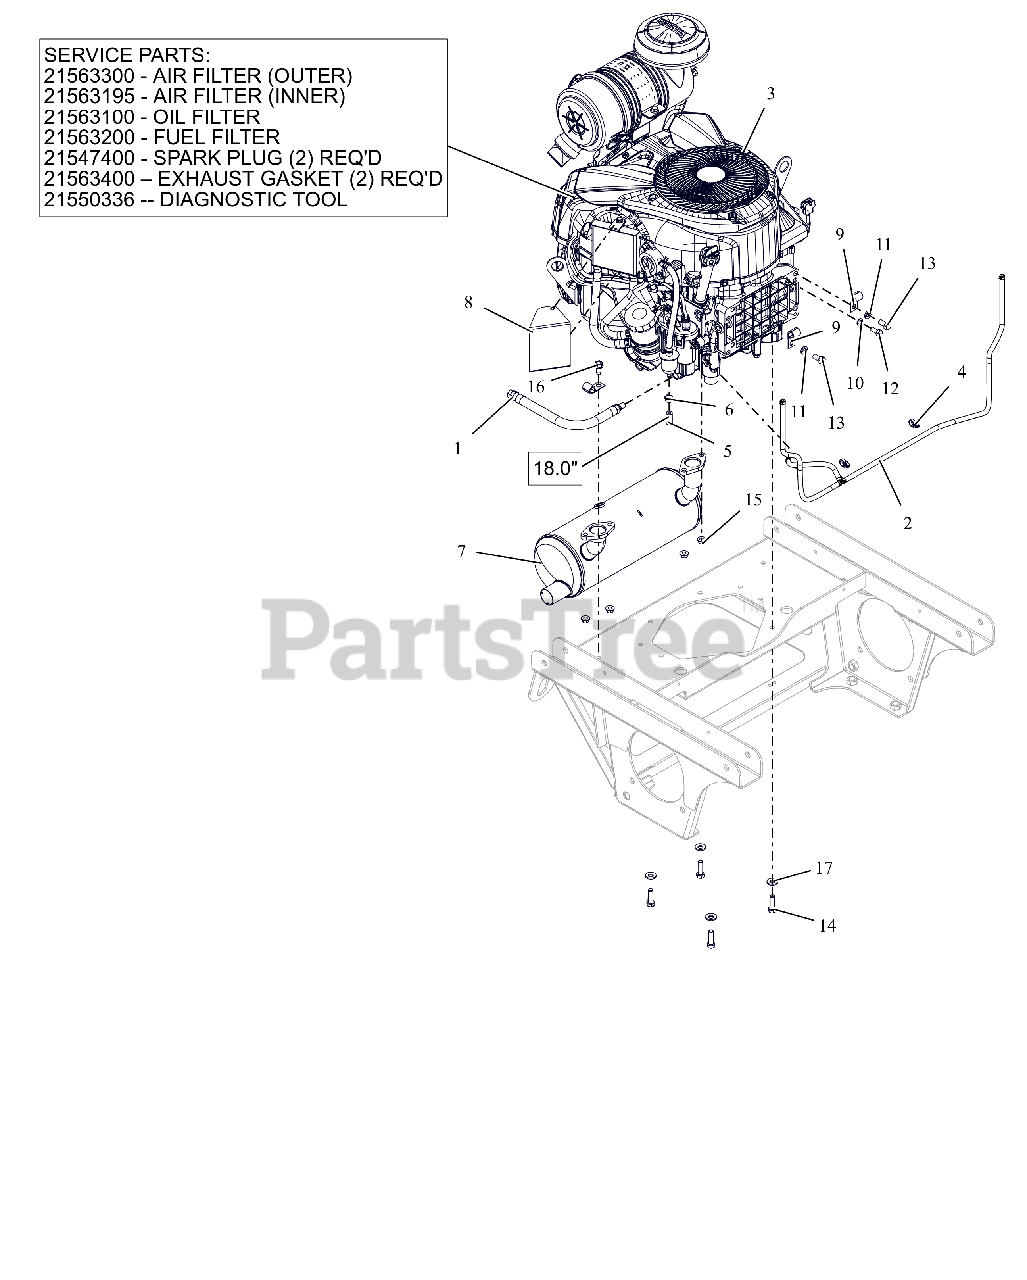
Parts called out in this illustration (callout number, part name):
1	HOSE, OIL DRAIN
2	ASM, YAMAHA VAPOR LINE
3	ENGINE, YAMAHA MX775V-EFI
3	AIR FILTER (OUTER) - YAMAHA
3	AIR FILTER (INNER) - YAMAHA
3	FILTER, OIL - YAMAHA 824
3	FILTER-FUEL YAMAHA 824
3	PLUG, SPARK
3	GASKET, MUFFLER YAMAHA 824
3	DIAGOSTIC TOOL, YAMAHA MXV
4	ROUTING CLIP (1/2" ID)
5	HOSE, .25 LOW-PERM BULK GAS
6	CLAMP, FUEL LINE
7	MUFFLER, YAMAHA
8	DEFLECTOR,YAMAH OIL COOLER AIR
10	WSHR,LK-REG .312X.078 ZCC
11	WSHR,LK-REG .375X.094 ZCC
12	BLT,HEX .31-18X.75 G5 ZCC
13	BLT,HEX .38-16X.75 G5 ZCC
14	BLT, HEX .38-16X1.25 G5 ZCC NT
15	NUT-LK-TOP-FLG M8 ZCC
16	SCR,TAP .375-16X.75 HWH TR ZCC
17	WASHER, 3/8" SPRING DISC
